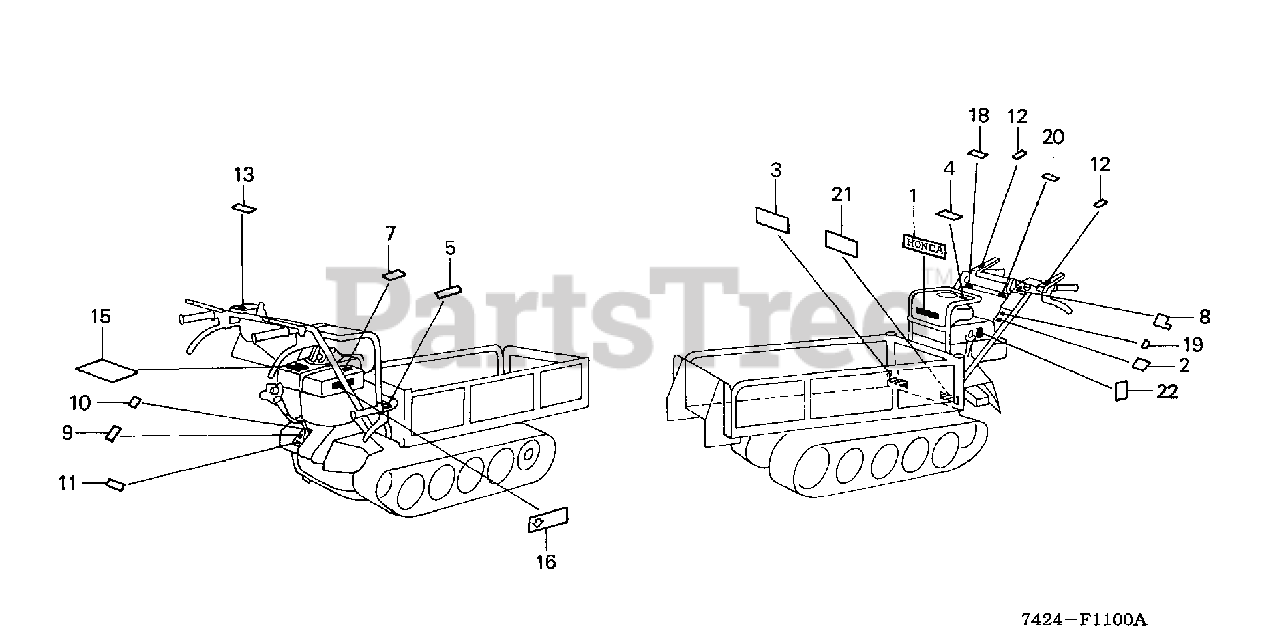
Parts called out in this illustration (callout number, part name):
1	EMBLEM
2	EMBLEM
3	MARK, CARRIER CAUTION (ENGLISH)
4	LABEL, FUEL CAUTION (ENGLISH)
5	MARK, LOCK LEVER
7	MARK, EASY START
8	MARK, ENGINE SWITCH (ENGLISH)
9	MARK, POSITION INDICATION (ENGLISH)
10	MARK, POSITION INDICATION
11	MARK, POSITION INDICATION
12	MARK, CLUTCH INDICATION (ENGLISH)
13	LABEL C, CAUTION
15	LABEL A, CAUTION
16	MARK, AIR CLEANER CAUTION (ENGLISH)
18	MARK, R. SIDE CLUTCH (ENGLISH)
19	MARK, THROTTLE (ENGLISH)
20	MARK, L. SIDE CLUTCH (ENGLISH)
21	LABEL, MAXIMUM WEIGHT CAUTION
22	MARK, OIL CAUTION
